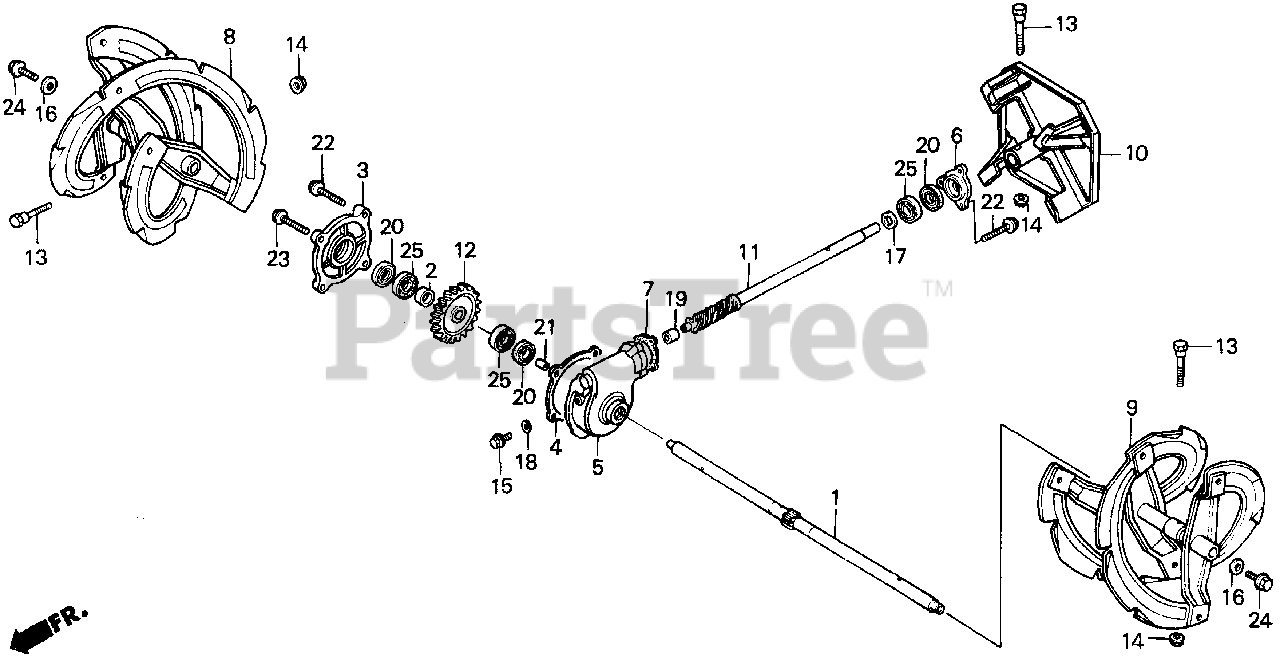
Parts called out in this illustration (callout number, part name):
1	SHAFT, AUGER (NOT AVAILABLE)
2	COLLAR, DISTANCE
3	COVER, AUGER TRANSMISSION (NOT AVAILABLE)
4	GASKET, AUGER TRANSMISSION
5	CASE, L. AUGER TRANSMISSION (NOT AVAILABLE)
6	CAP, AUGER CASE (NOT AVAILABLE)
7	GASKET, AUGER CASE
10	BLOWER (14")
11	GEAR, DRIVE (14")
12	GEAR, DRIVEN (NOT AVAILABLE)
13	BOLT, LOCK
14	NUT, SELF-LOCK (6MM)
15	BOLT, DRAIN PLUG
16	WASHER (8MM)
17	WASHER, THRUST (27X20X1.0)
18	WASHER, DRAIN PLUG (10.2MM)
19	BEARING, NEEDLE (15MM)
20	OIL SEAL (20X32X7)
21	PIN A, DOWEL (8X14)
22	BOLT, FLANGE (6X20)
23	BOLT, FLANGE (6X28)
24	BOLT, FLANGE (8X16)
25	BEARING, RADIAL BALL (6004)
